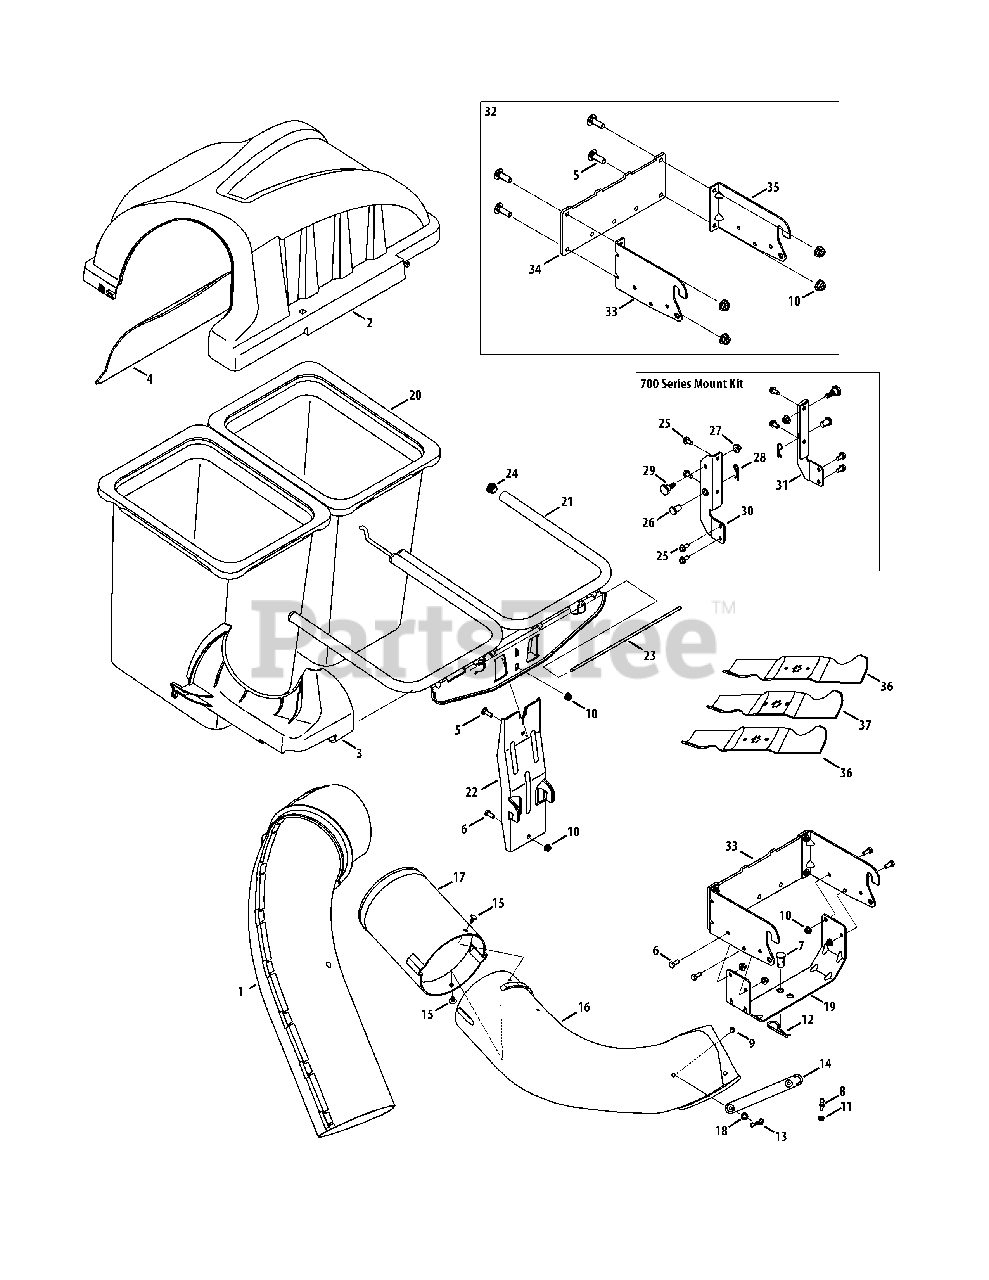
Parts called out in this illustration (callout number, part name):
1	Upper Chute Assembly
2	Double Bagger Cover Assembly
3	Upper Chute Support
4	Bagger Cover Screen
5	Carriage Screw, 5/16-18 x 1.00"
6	Hex Head Screw, 5/16-18 x .75"
7	Clevis Pin, .62" Dia.
8	Grass-catcher Pin, 1/4-20
9	Clevis Pin, 5/16 x .75 Lg.
10	Flange Lock Nut, 5/16-18
11	Flange Lock Nut, 1/4-20
12	Internal Cotter Pin, .148 x 3.00
13	Bow-Tie Cotter Pin, 72
14	Chute Strap, 6.00 Lg.
15	Ratchet Clip, .250
16	Discharge Chute Elbow, 46" Deck
17	Bagger Chute Adapter, 7 In.
18	Flat Washer, .344 x .62 x .033
20	Grass-bag Assembly
21	Double Bag Support Assembly
22	Vertical Support Bracket
23	Cover Hinge Pin
24	End Plug
25	Tap Screw, 5/16-18 x .750
26	Clevis Pin, .50 x .78 Lg.
27	Flange Lock Nut, 3/8-16
28	Click Pin, .092 x 1.64 Lg.
29	Shoulder Screw, .625 x .412
30	Mounting Bracket, RH
31	Mounting Bracket, LH
32	Hitch Bracket Assembly (Incl. 33-35)
33	Hitch Bracket, RH
34	Universal Rear Attachment Bracket
35	Hitch Bracket, LH
36	Blade, 16.28 Lg., Star 2-in-1
37	Blade, 14.88 Lg., Star 2-in-1
